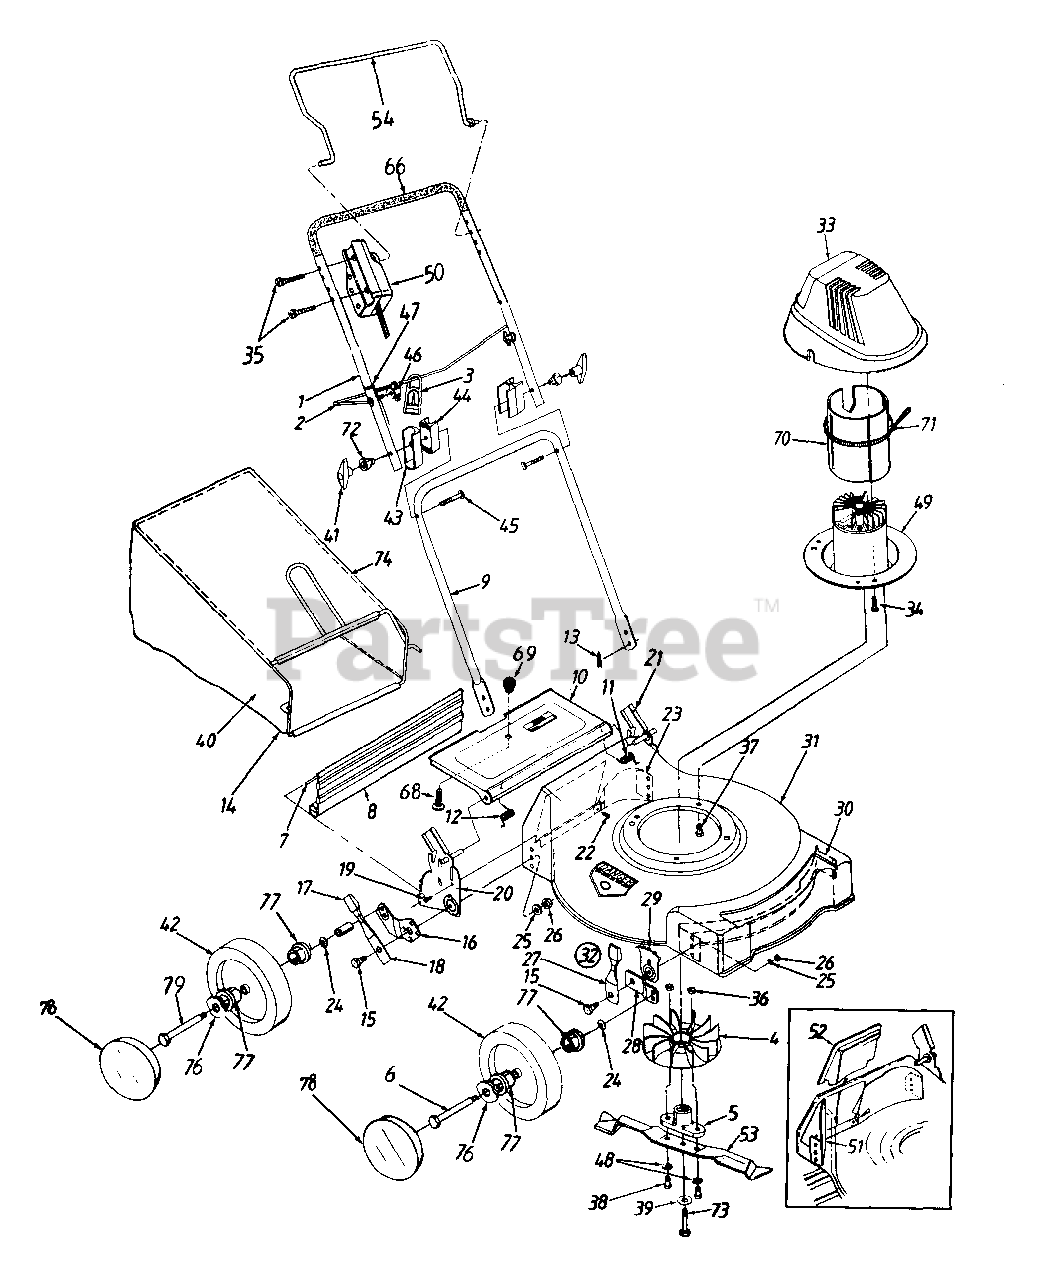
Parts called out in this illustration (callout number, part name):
3	Strain Relief - Cord
4	Fan
5	Blade Adapter
6	Front Axle Bolt
7	Rear Flap Wire
8	Rear Flap
9	Lower Handle
10	Chute Door
11	Door Spring - L.H.
12	Door Spring - R.H.
13	Hairpin Clip
16	Pivot Bar - R.H.
16	Pivot Bar - L.H.
17	Spring Lever Knob
18	Spring Lever
19	Hex L-Wash. Hd. AB-Tap Scr. 1/4 x .62" Lg.
20	Handle Brkt. Ass'y. - R.H.
21	Handle Brkt. Ass'y. - L.H.
22	Torx . Mach. AB-Tap Scr. 1/4 x .62" Lg.
23	Rear Baffle
24	Bell-Wash..38" I.D. x .88" O.D.
25	Bell-Wash..39" I.D. x 1.38" O.D.
26	Hex Nut 3/8-16 Thd.
27	Spring Lever Ass'y. w/Knob
29	Height Adj. Plate
30	Front Baffle
32	Height Adj. Ass'y. Comp. - L.H.
33	Motor Cover
34	Scr. #10-16 x .75" Lg.
35	C-Sunk Scr. 1/4-20 x 1.8" Lg.
36	Hex Nut 3/8-24 Thd.
37	Hex L-Wash. TT-Tap Scr. 3/8-16 x .75" Lg.
38	Hex Bolt 3/8-24 x 1.25" Lg.
39	Bell-Wash. .396" I.D. x 1.14"
40	Grass Bag
41	Plastic Knob
42	Wheel Ass'y. Comp.
43	Upper Handle Insulator
44	Lower Handle Insulator
45	Carriage Bolt 5/16-18 x 3" Lg.
46	Wing Nut 1/4-20 Thd.
47	Cable Tie
48	Bell-Wash. 3/8" I.D.
49	Motor, Cord & Switch Ass'y.
50	Cord & Switch Ass'y. Comp.
51	Mulching Baffle - R.R.
52	Mulching Baffle Plug
53	19" Mulching Blade
54	Control Handle
66	Foam Grip
68	Truss Scr. #10-24 x .38" Lg.
70	Insulator
71	Cable Tie
72	Insulator Knob
73	Hex Bolt 3/8-24 x 2.5" Lg.
74	Rear Catcher Frame
76	Wave Washer
77	Bell Bearing
78	Hub Cap
79	Rear Axle Bolt
80	Spacer
